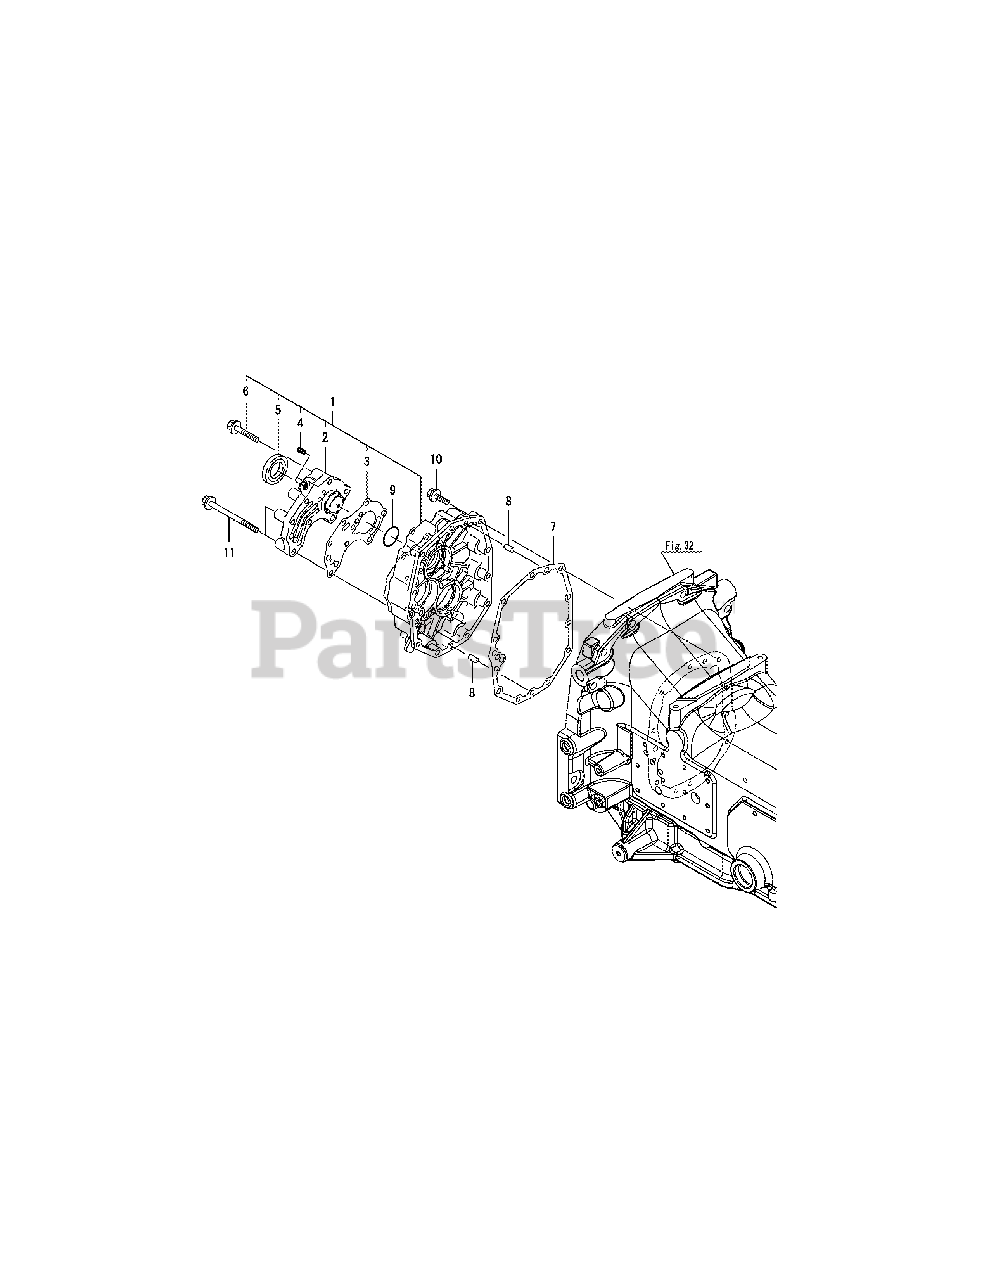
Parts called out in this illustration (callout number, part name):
1	COVER ASSY, FRONT
4	PLUG PT1/8,SCREW
6	BOLT M 8X 50 PLATED
7	GASKET, FRONT COVER
8	PARALLEL PIN, M8X16
9	O-RING 1A S-35.0
10	BOLT M 8X 35 PLATED
11	BOLT M 8X110 PLATED
